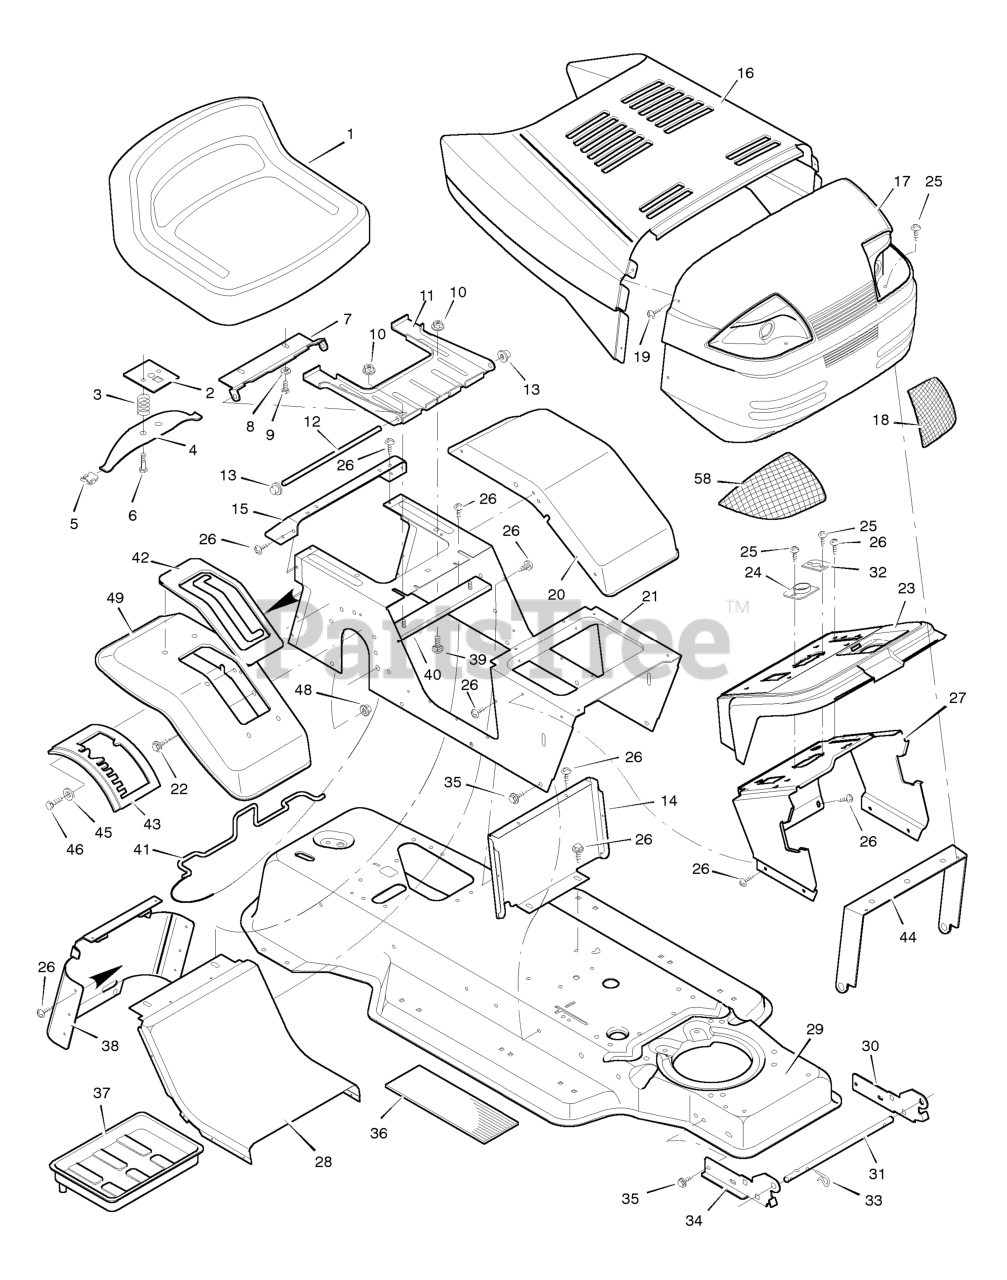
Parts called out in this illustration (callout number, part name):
2	Plate Assembly, Switch
3	Spring, Compression
4	Spring, Seat
5	Glide, Spring
6	Bolt, Shoulder
7	Support, Seat
8	Lockwasher
9	Bolt, Hex
10	Locknut, Flange
11	Bracket, Pivot
12	Rod, Pivot
13	Cap, Push On
14	Insert, Front
15	Fender, Apron
17	Grille Assembly
18	Lens, Left
21	Console Assembly
23	Dash Panel
24	Bearing, Steering
26	Screw
27	Support, Dash
28	Insert, Rear
29	Frame Assembly
30	Bracket, Left Grille
31	Rod, Pivot
32	Bearing
33	Pin, Hair
34	Bracket, Right Grille
37	Tray, Battery
38	Cap, Console
39	Bolt
40	Channel Assembly
41	Clamp, Battery
42	Cover, Shift
43	Gate, Shift
44	Brace, Grille
45	Washer
46	Bolt, Hex
48	Locknut
49	Fender, SOG
58	Lens, Right
